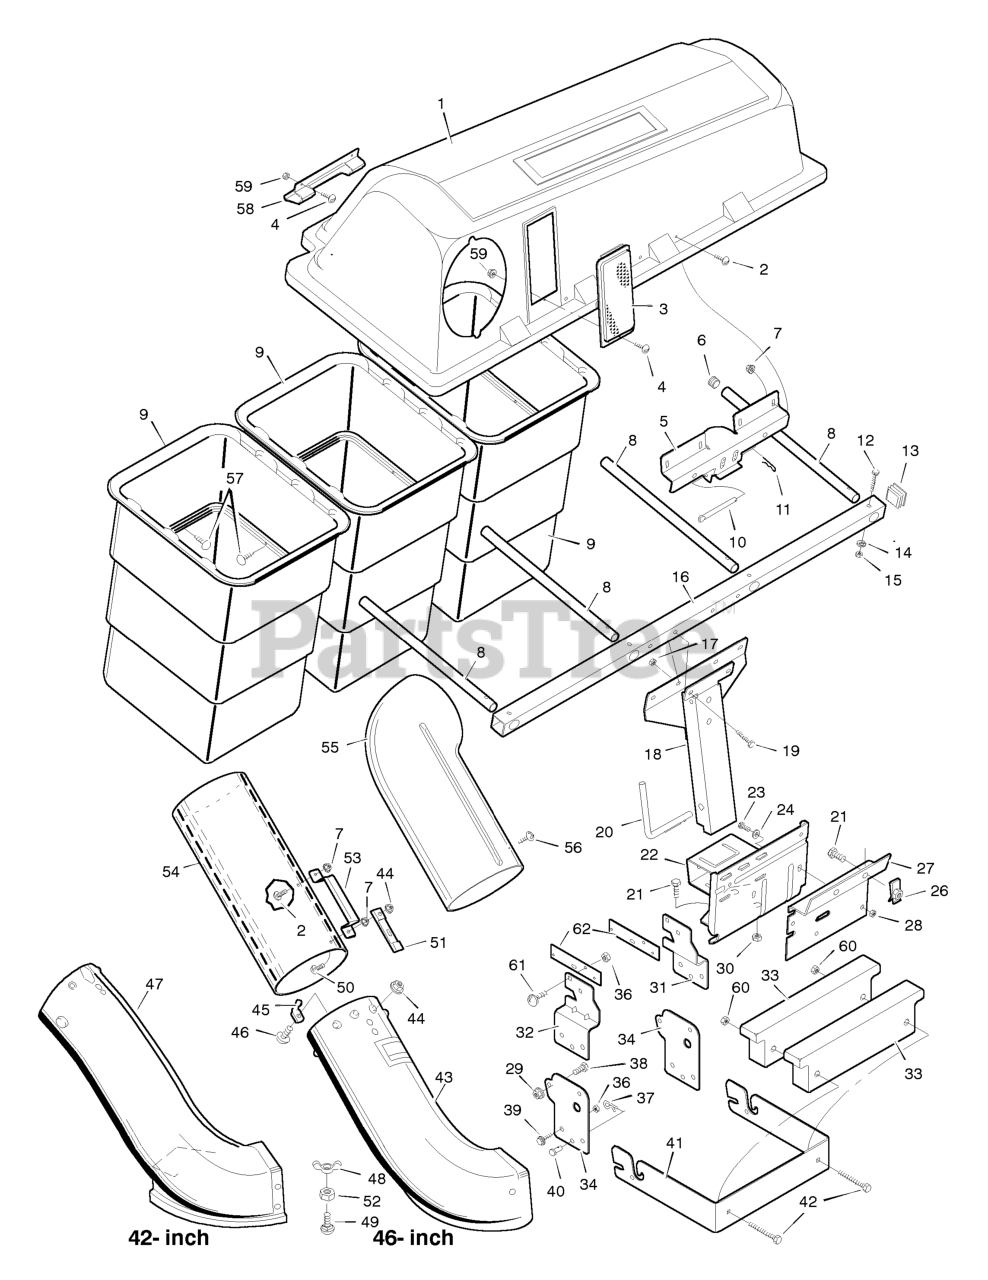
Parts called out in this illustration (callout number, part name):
1	Cover, Bagger
5	Hinge, Bracket
7	Nut, Hex
8	Tube, Container
9	Container
10	Pin, Cover Hinge
11	Pin, Hair
13	Plug
14	Lockwasher
16	Tube, Support
17	Nut
18	Assembly, Channel
20	Pin, Channel Mount
21	Bolt, Hex
22	Assembly, Bagger Mount
23	CAPSCREW, Hex Head, 5/16-18 x 1
24	Washer
27	Adapter, Bracket
28	Nut, Super Flange
29	Nut, Flange
30	Nut, Hex
31	Bracket, Left Hanger
32	Bracket, Right Hanger
33	Weight, Front
34	Bracket, Hanger
36	Nut
37	Pin, Hair
38	Bolt
40	Pin, Clevis
41	Bracket, Front Weight
43	Extension, Chute
44	Locknut, Flange
45	Pin, Latch
46	Bolt, Carriage
47	Extension, Chute
48	Wingnut
49	Bolt, Carriage
51	Latch, Rubber
53	HANDLE, Connect Tube
54	Tube, Connecting
57	Fastener, Panel
58	Handle, Plastic
59	Nut, Hex
60	Nut
62	Plate, Support
